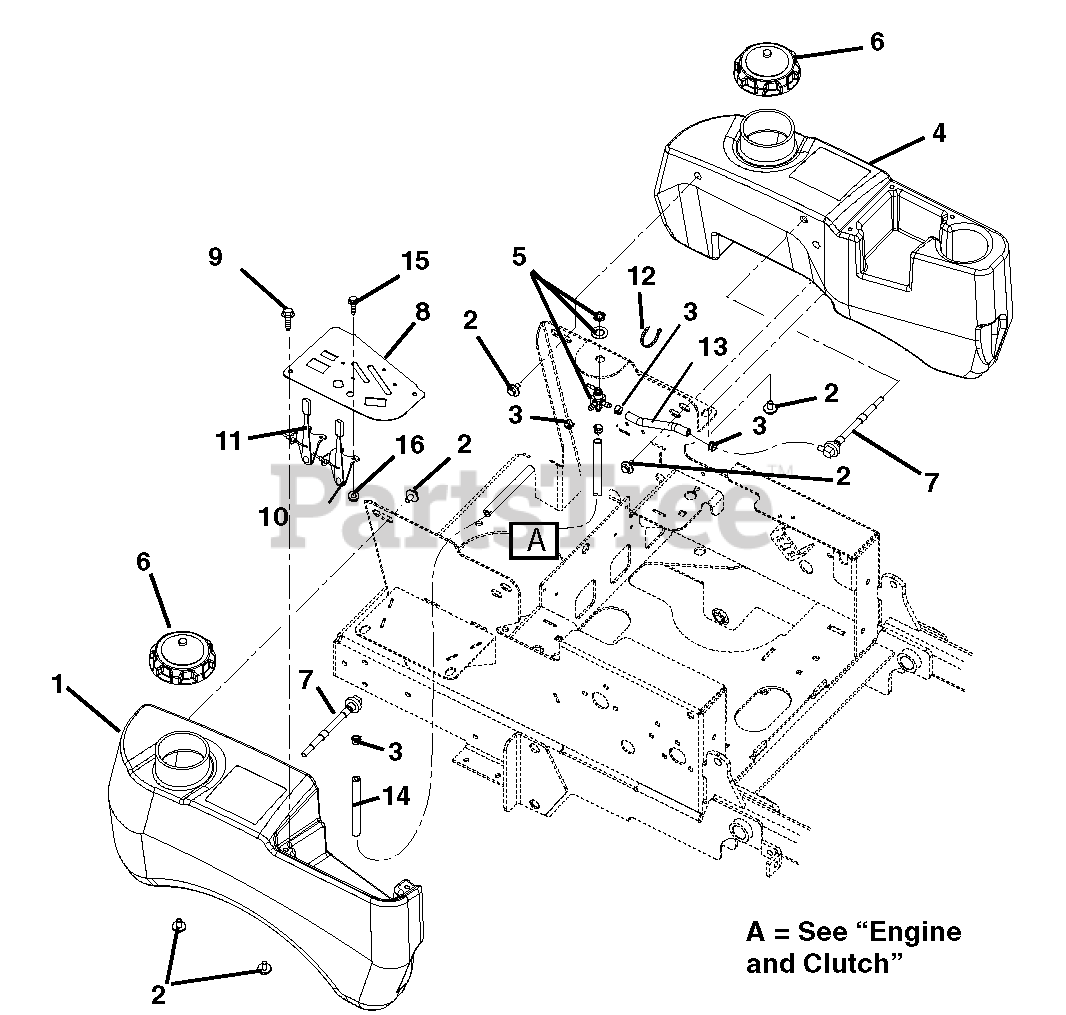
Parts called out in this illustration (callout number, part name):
1	Tank, Gas- Right Hand
2	Bolt, SEMS .31-18 x .62
3	Clamp, Fuel Line
4	Tank, Left Hand Fuel 100 S. without Hose
5	Valve, Fuel
6	Cap, Fuel
7	Assembly, Small Tank Fuel Pick-up
8	Panel, Control
9	Screw, Machine 10-24 x .50
10	Cable, Control
11	Cable, Throttle OR Choke
12	Cable Tie
13	Hose, .25 Low-PERM Bulk Gas
14	Hose, .25 Low-PERM Bulk Gas
15	Screw, Machine 10-24 x .50 Hex Washer Head
16	Nut, Locking-Nylon 10-24 with Insert
